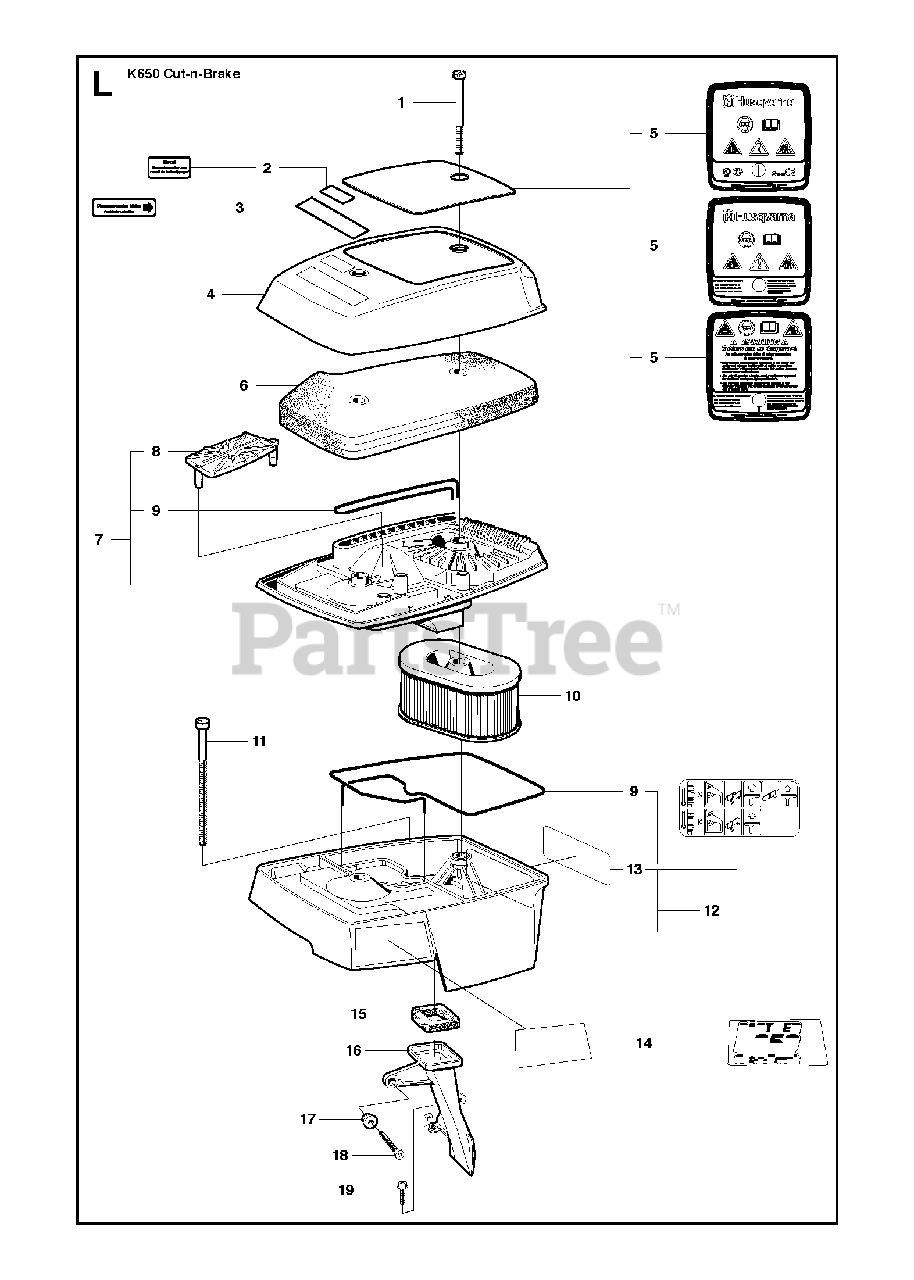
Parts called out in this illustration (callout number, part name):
5	LABELEPA USA
7	FILTER BOTTOMIncl. 8, 9
9	ELASTIC STRING
12	CYLINDER COVERIncl. 9, 13
18	SCREW IHSCM
